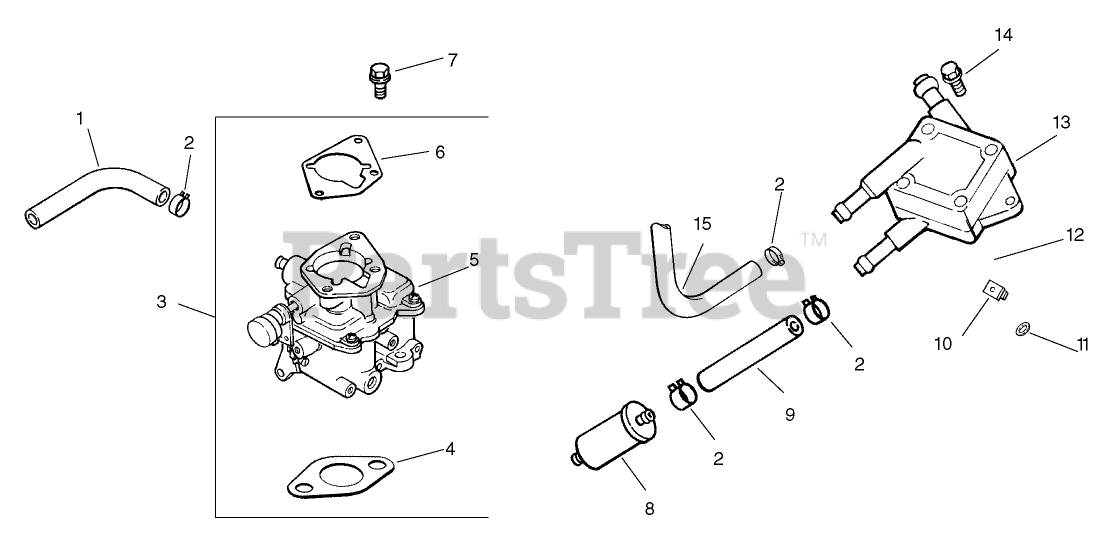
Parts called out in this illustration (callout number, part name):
1	Line-Fuel (9.5)
2	CLAMP-HOSE, SPRING (1/2)
3	Kit-Carburetor w/ Gasket (Incl. Ref. # 4-6)
4	GASKET-BASE, AIR CLEANER
6	Gasket-Carburetor
7	SCREW-FLANGE (M6X1.0X30)
8	Filter-Fuel
9	Line-Fuel
10	Nut-Plastic
10	PUMP-FUEL
11	Spacer
12	Washer-Flat (1/4)
13	PUMP-FUEL
14	Screw
15	Line-Fuel, Flexible (15.5)
